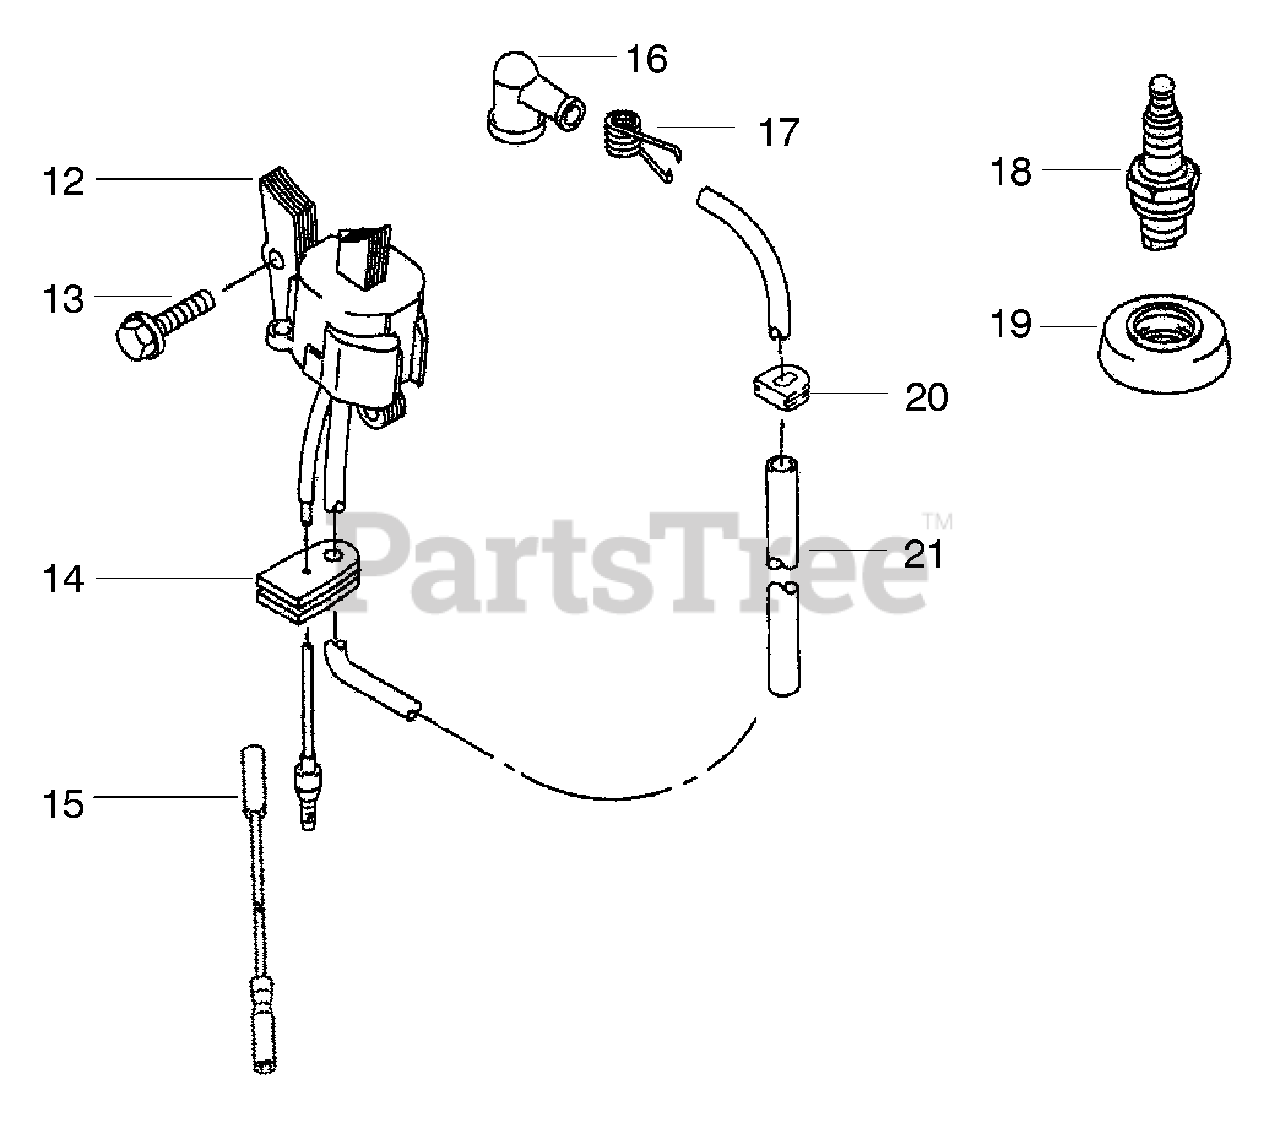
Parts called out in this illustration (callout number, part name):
12	Assy-Ignition Coil
15	Wire-Lead
16	Cap-Spark Plug
17	Terminal
18	Plug-Spark NGK (BPMR7A)solid
21	Tube-6x7.4x300
